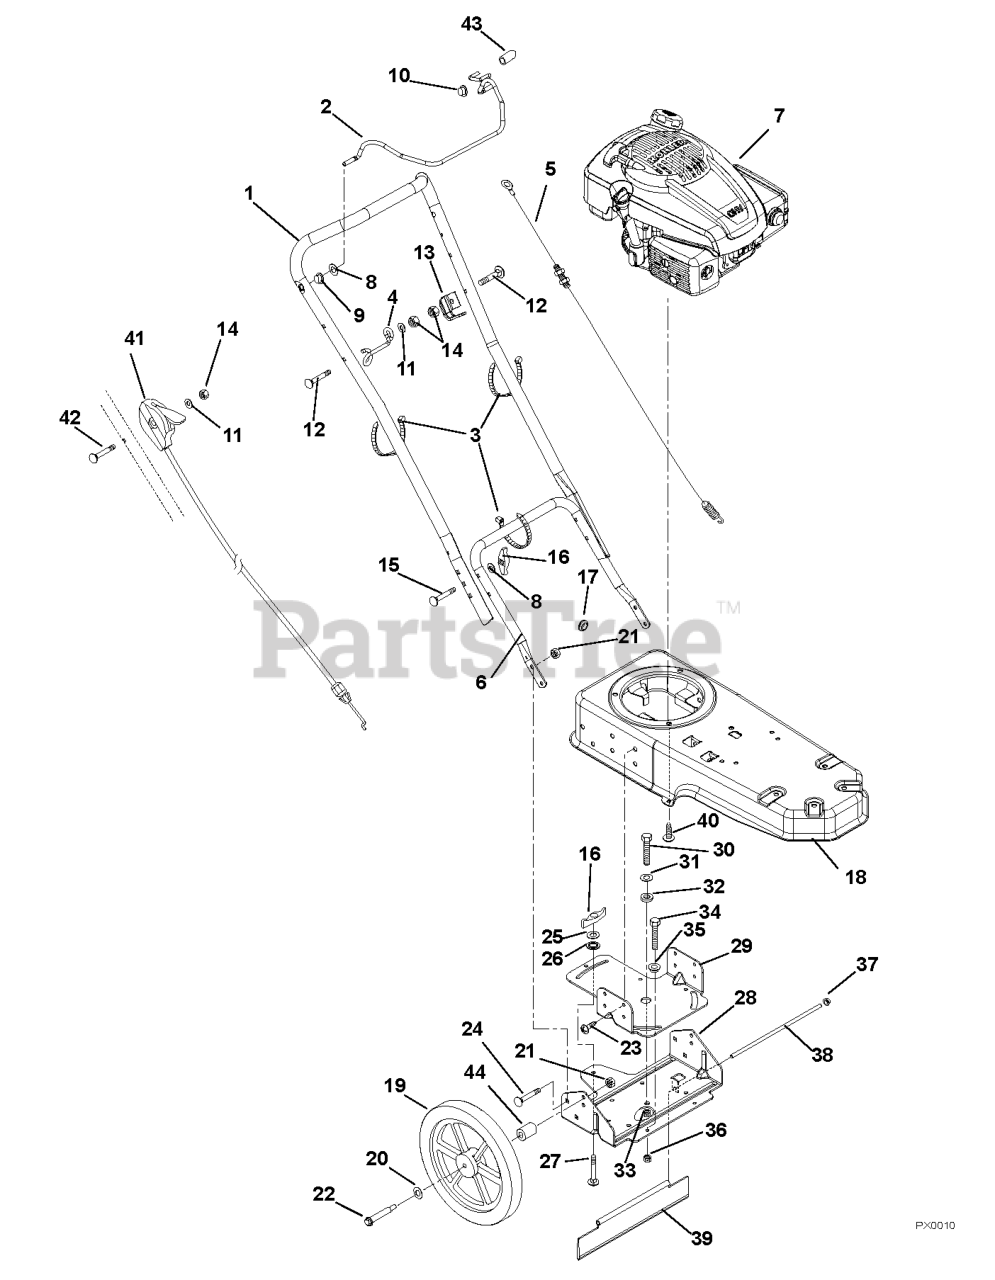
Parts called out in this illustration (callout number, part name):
1	Handlebar-Upper
2	Bail-Clutch Control
3	Cable-Tie
4	Guide-Pullcord
5	Cable-Control
6	Handlebar-Lower
7	Engine, Courage XT-8, Kohler
8	Washer-Flat-Steel .344 x .688 x .065
9	Bushing-Flange .325 x .444 x .440 x .560
10	Nut-Push .25
11	Washer-Flat-Steel .281 x .62 x .065
12	Bolt-Round Head Extra Long Square Neck .25-20 x 1.25
13	Cable-Anchor
14	Nut-Locking-Center .25-20
15	Bolt-Round Head Square Neck Full Thread .31-18 x 2.00 Grade 5
16	Knob-Wing .312-18
17	Grommet .50 I.D.
18	Frame-Trimmer
19	Wheel 14" String Trimmer
20	Washer-Flat-Steel .52 x .827 x .062
21	Nut-Locking-Center .38-16
22	Bolt-Shoulder .38-16 x 2.50
23	Screw-Tapping .38-16 x .75
24	Bolt-Round Head Square Neck .38-16 x .75 Grade 5
25	Washer-Flat-Steel .38 x .875 x .083
26	Nut-Push .312
27	Bolt-Round Head Square Neck .31-18 x 1.00
28	Bracket-Axle Swivel
29	Base-Swivel
30	Bolt-Hex .50-13 x 1.00 Grade 5
31	Washer-Flat-Steel .562 x 1.38 x .109
33	Nut-Locking-Center .50-13
34	Bolt-Hex .31-18 x 1.00
35	Bushing Flange .312 x .500 x .344 x .880
36	Nut-Locking-Center .31-18
37	Nut-Push .312
39	Guard-Rear-Swivel
40	Screw-Tapping .38-16 x 1.00
41	Cable, Throttle
42	Bolt-Round Head Extra Long Square Neck .25-20 x 1.75
43	Cap-Vinyl .25 I.D.
44	Bushing, Sleeve .377 x .624 x .235
